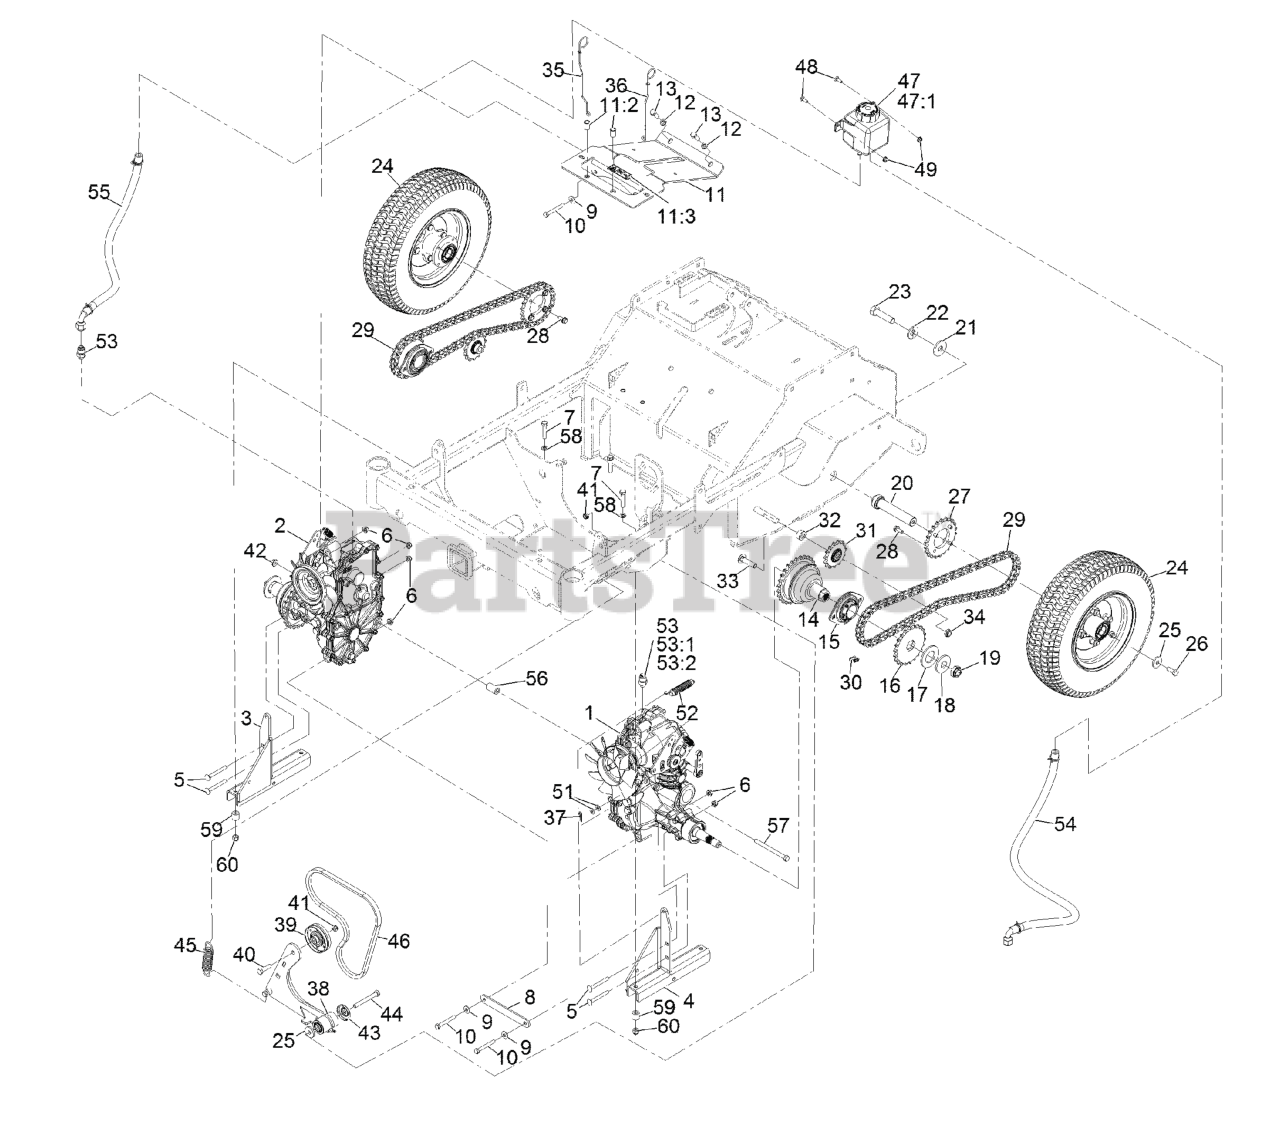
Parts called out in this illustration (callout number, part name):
1	HYDRO-ZT3100, LH
2	HYDRO-ZT3100, RH
3	MOUNT-HYDRO, RH
4	MOUNT-HYDRO, LH
5	SCREW-CARR
6	NUT-HF, NI
7	SCREW-HH
8	Crossmember-Transmission
9	WASHER-SPRING
10	SCREW-HH
11	SUPPORT-COVER
11:2	NUT-CLINCH
11:3	DECAL-DANGER
12	WASHER-LOCK
13	SCREW-HH
14	HUB-BELL
15	BEARING-FLANGED
16	SPROCKET
17	WASHER-SPACER
18	Washer-Belleville
19	NUT-LOCK
20	AXLE-WHEEL, DRIVE
21	WASHER-SPACER
22	Washer-Belleville
23	Screw-HH
24	WHEEL AND TIRE ASM
25	Washer-Flat
26	SCREW-HH, LOCK
27	SPROCKET
28	SCREW-HHF
29	CHAIN-ROLLER
30	LINK-CONNECTING
31	SPROCKET-IDLER, 15T
33	Screw-CARR
34	NUT-HEX
35	ROD-BYPASS, LH
36	ROD-BYPASS, RH
38	IDLER ARM ASM
39	PULLEY-IDLER
40	SCREW-HH
42	NUT-HF, NI
43	GUARD-TOP
44	SCREW-HH
45	SPRING-EXTENSION
46	BELT-V, COGGED
47	TANK-HYD
47:1	CAP-RESERVOIR, HYD
48	BOLT-CARR
52	SPRING-EXTENSION
53	FITTING-STRAIGHT
53:1	O-RING
54	HOSE ASM
55	HOSE ASM
57	SCREW-HH
58	SPACER-BRAKE, PARKING
60	NUT-LOCK
